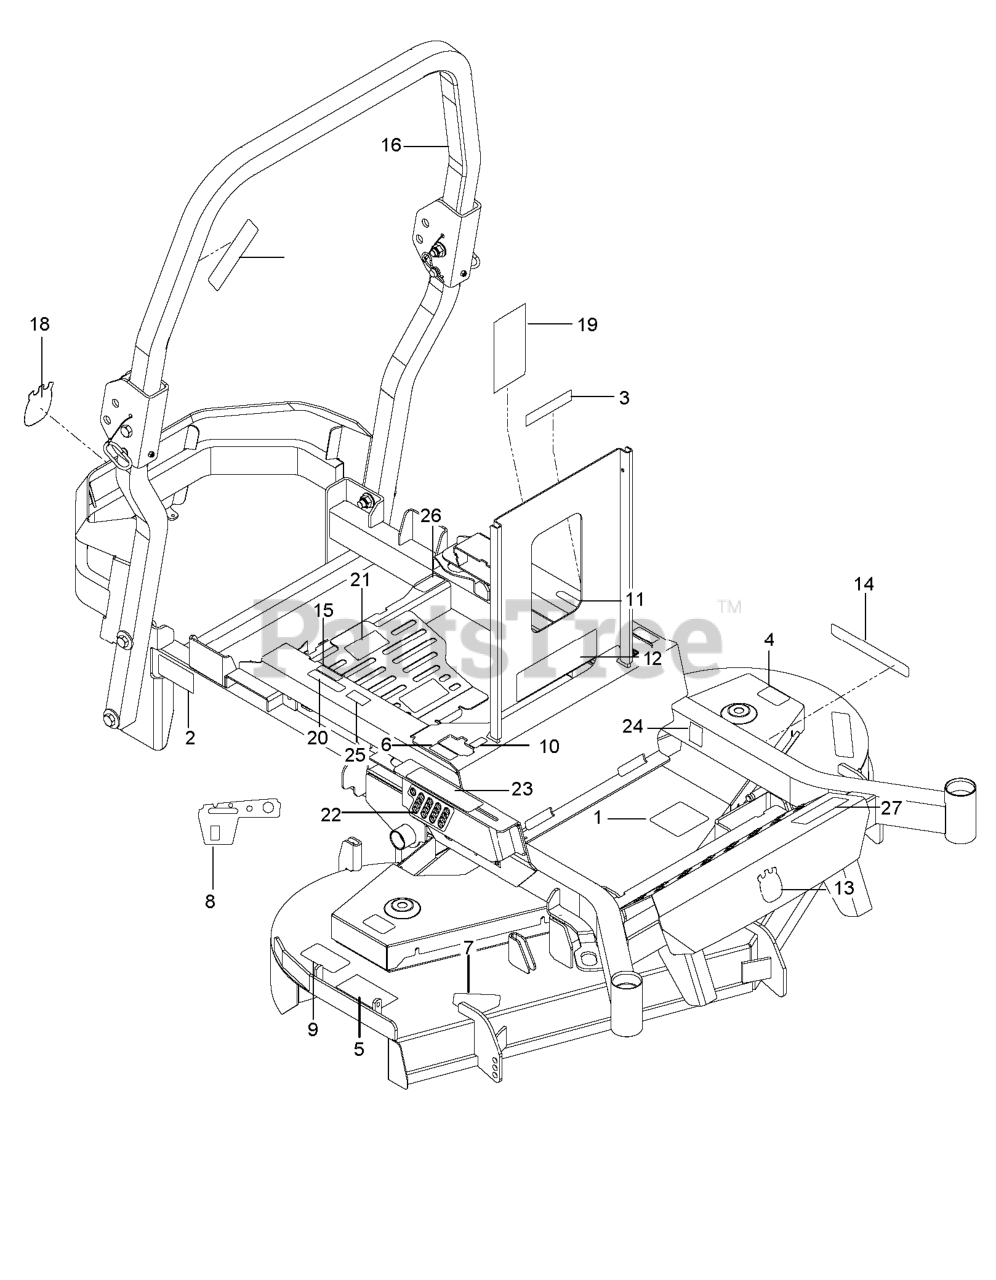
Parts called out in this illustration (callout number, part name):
1	DECAL, BELT ROUTING
2	DECAL, BELT DRIVE
3	EURO DECAL-BATTERY WARNIN6
4	DECAL, NO STEP
5	DECAL, EURO SEVERING
6	DECAL, MOTION CONTROL
7	DECAL, CPSC
8	DECAL, CONTROL, GAS
9	DECAL, CAUTION
10	DECAL, F.S.T.
11	DECAL, PARK BRAKE
12	DECAL, WARNING
13	DECAL.AUGER.HUSQ.CROWN.SNOW
14	RP.DECAL.BADGE.170MM.TEXTLOGO
15	DECAL, FUSE
16	DECAL, ROPS
17	DECAL, ROPS, WARNING
18	DECAL, CROWN H, 110MM
19	DECAL, SERVICE
20	DECAL, WARNING SPARK ARRESTOR
21	HG_DECAL, ZT-3400
22	DECAL, HEIGHT
23	DECAL, RELEASE LEVER
24	DECAL 80 DBA
25	DECAL, ECM, AUSTRALIA
26	DECAL, FUEL
